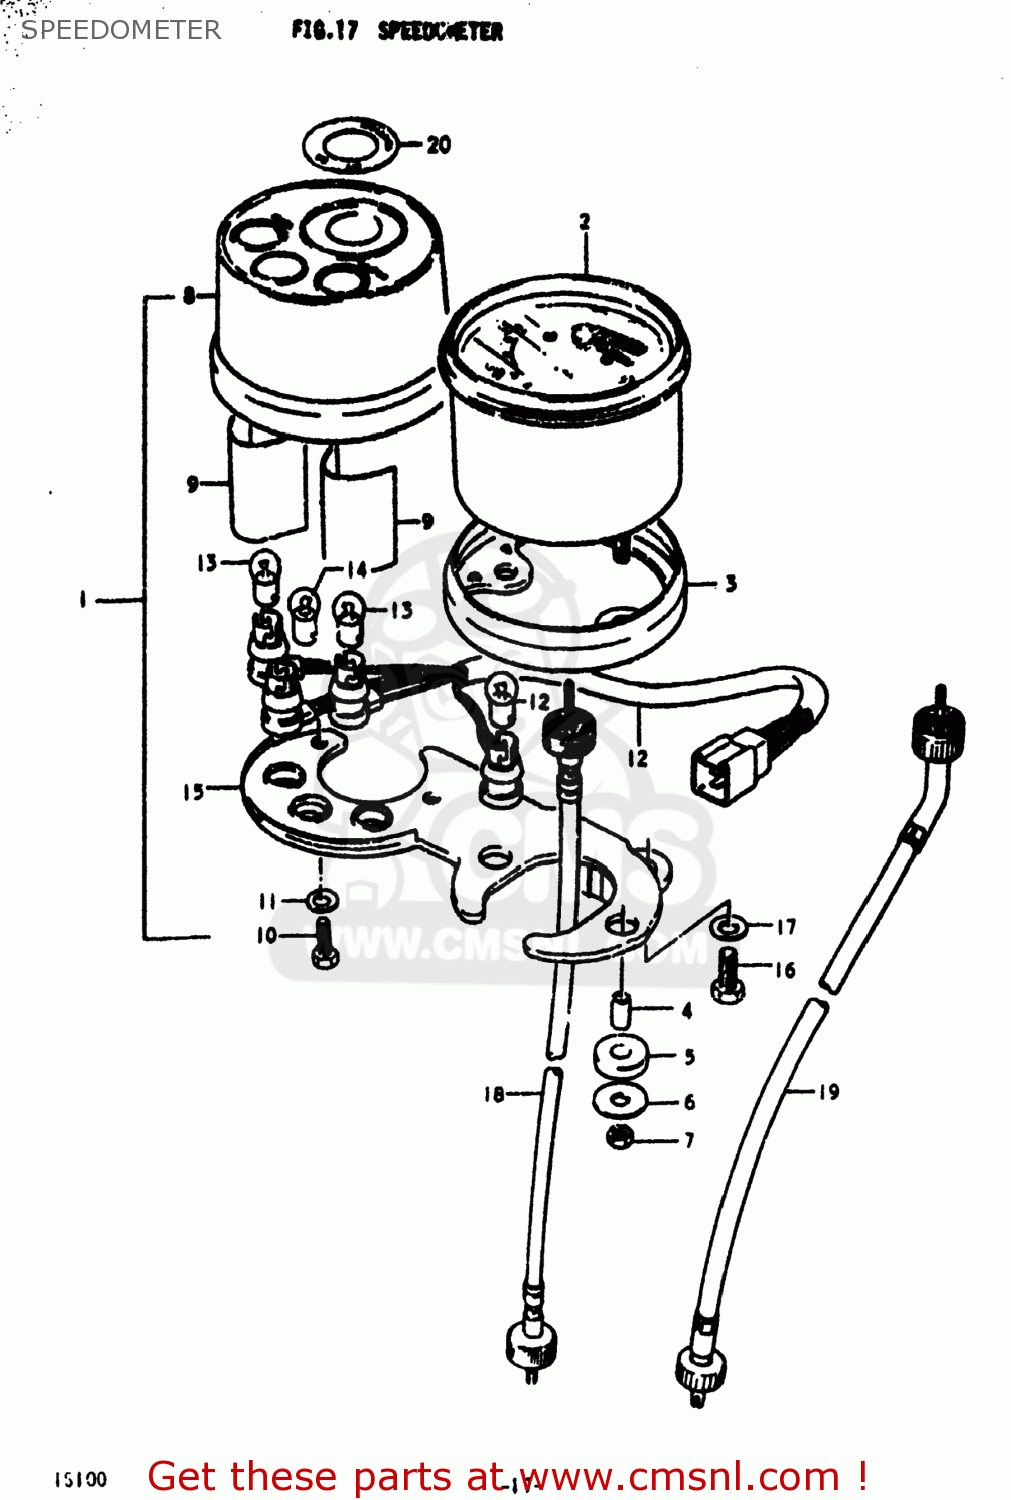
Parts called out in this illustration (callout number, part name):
1	SPEEDOMETER ASSEMBLY
2	SPEEDOMETER ASSEMBLY
3	CUSHION
4	SPACER
5	CUSHION,SPEEDOMETER
6	WASHER (5.5X18X1.6)
7	NUT
8	CASE,PILOT BULB
9	REFLECTOR,PILOT LAMP
10	BOLT
11	WASHER
12	SOCKET,METER
13	BULB(6V/3W)
14	BULB(6V1.7W,STANLEY,A61A)
15	BRACKET,SPEEDOMETER
16	BOLT 8X12
17	WASHER
18	CABLE ASSY,SPEEDOMETER
19	CABLE ASSEMBLY,SPEEDOMETER
